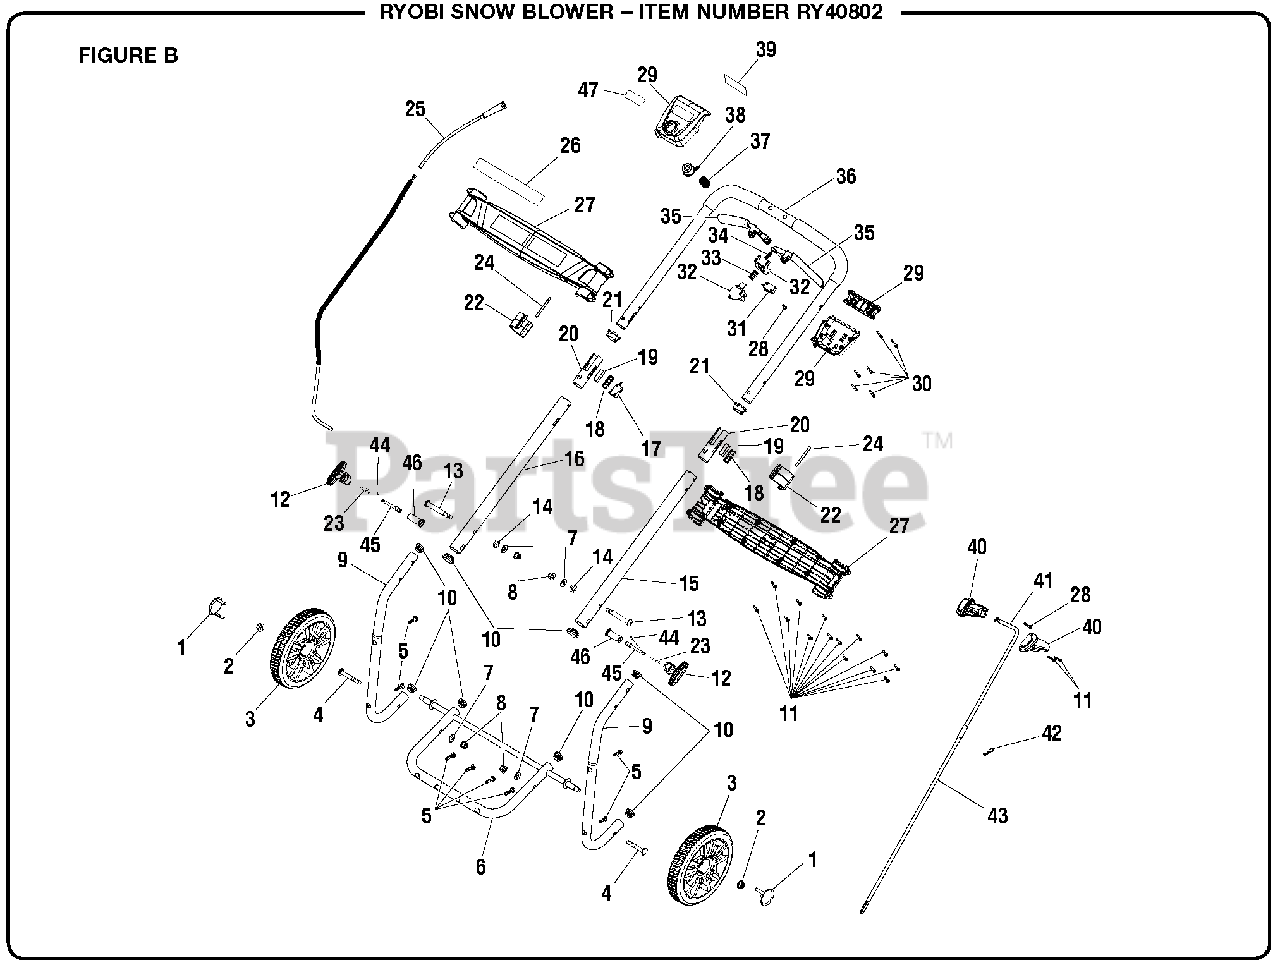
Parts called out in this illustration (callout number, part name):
1	Wheel Cover (Light Grey)
2	Lock Nut (3/8-16)
3	8 in. Wheel Assembly
4	Screw (M8 x 62 mm, Special Hd.)
5	Screw (1/4 - 15, T30 Torx Pan Hd.)
6	Lower Support Tube and Axle Assembly
7	Washer (ID8.5 x OD20.5 x 2 mm x 2t)
8	Flange Lock Nut (M8 x 1.25 mm)
9	Lower Handle
10	End Cap Set (22 mm)
11	Screw (4 X 18 mm, T15 Torx Pan Hd.)
12	Spring Pin Adjustment Knob
13	Screw (M8 x 73 mm, T40 Torx Button Hd.)
14	Block Washer (ID10.4 x OD22 x 6.75t)
15	Left Middle Straight Tube
16	Middle Straight Tube
18	Locking Block
19	Rubber Gasket
20	Handle Tube Bushing
21	Straight Tube Bushing
22	Telescoping Latch
23	Compression Spring
25	Strain Relief and Short Cable Assembly
26	Mid Panel Logo Label
27	Mid Trim Housing Assembly
28	Screw (M4 x 10 mm, T20 Torx Pan Hd.)
29	Trigger Housing Assembly
30	Screw (M4 x 30 mm, T15 Torx Soc. Hd.)
32	Switch Button Assembly
33	Compression Spring (Trigger Handle)
34	Compression Spring (Trigger)
35	Trigger Assembly
36	Upper Handle Assembly
37	Compression Spring
38	Safety Button
39	Start Label
40	Chute Handle Assembly
41	Upper Rod
42	Hitch Pin
43	Lower Rod
44	Spring Pin
45	Detent Pin
46	Spring Pin Housing
47	Logo Label
